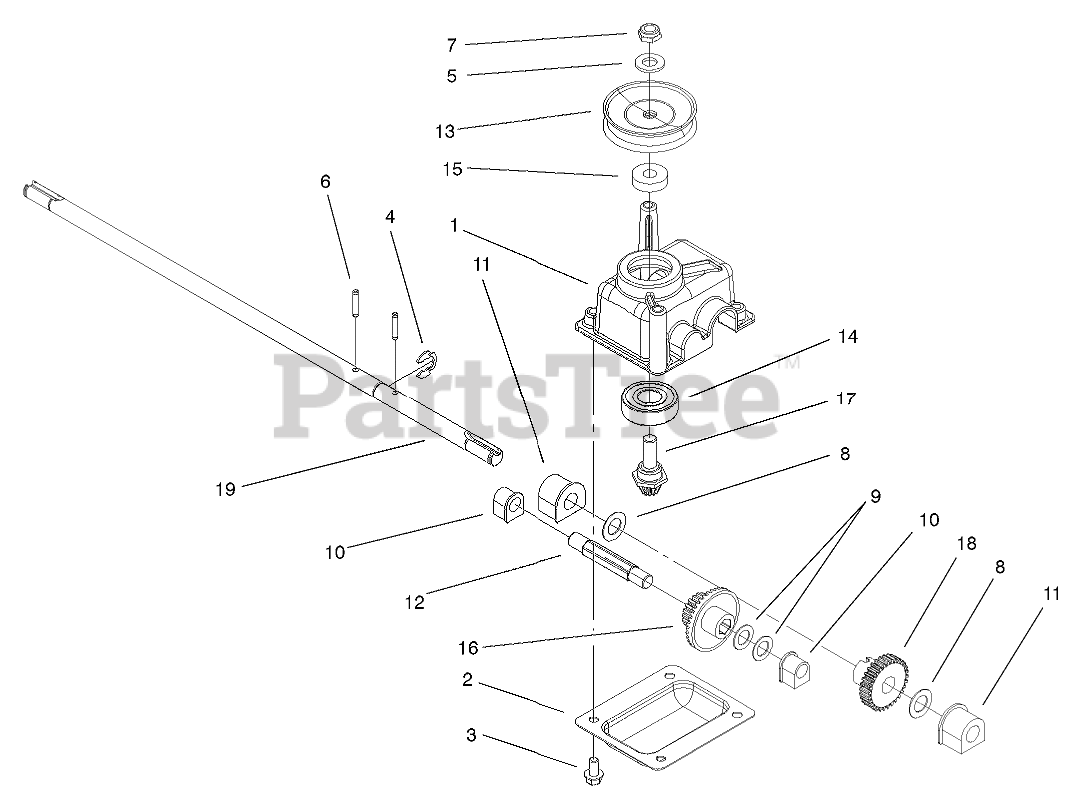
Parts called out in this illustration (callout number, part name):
1	CASE-GEAR
2	COVER-CASE, GEAR
3	SCREW-HWH
4	RING-RETAINING
5	WASHER-FLAT
6	PIN-GROOVE
7	NUT-HEX
8	WASHER-PLAIN
9	WASHER-THRUST
10	BUSHING
11	BUSHING
12	SHAFT-INTERMEDIATE
13	PULLEY-HALF
14	BEARING-BALL
15	SPACER
16	GEAR-19T SPUR, 37T BEVEL
17	GEAR-PINION, BEVEL
18	GEAR-30T
19	SHAFT-OUTPUT
